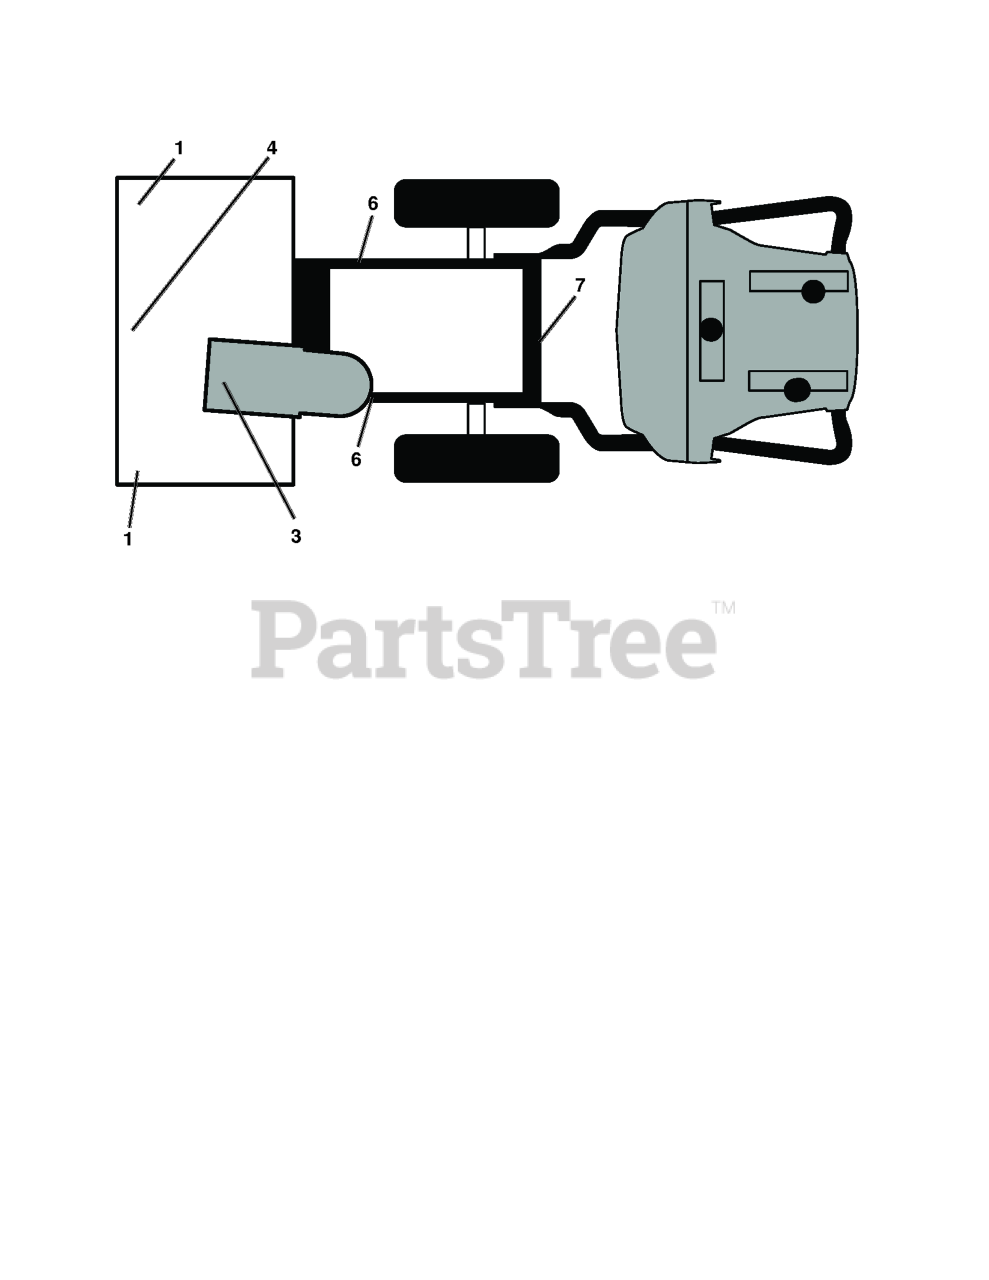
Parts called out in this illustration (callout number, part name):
1	DECAL.AUGER.SAFETY.
3	DECAL.CHUTE.SAFETY.
4	DECAL.AUGER."
6	DECAL.BELT.GUARD.
7	DECAL.FENDER
